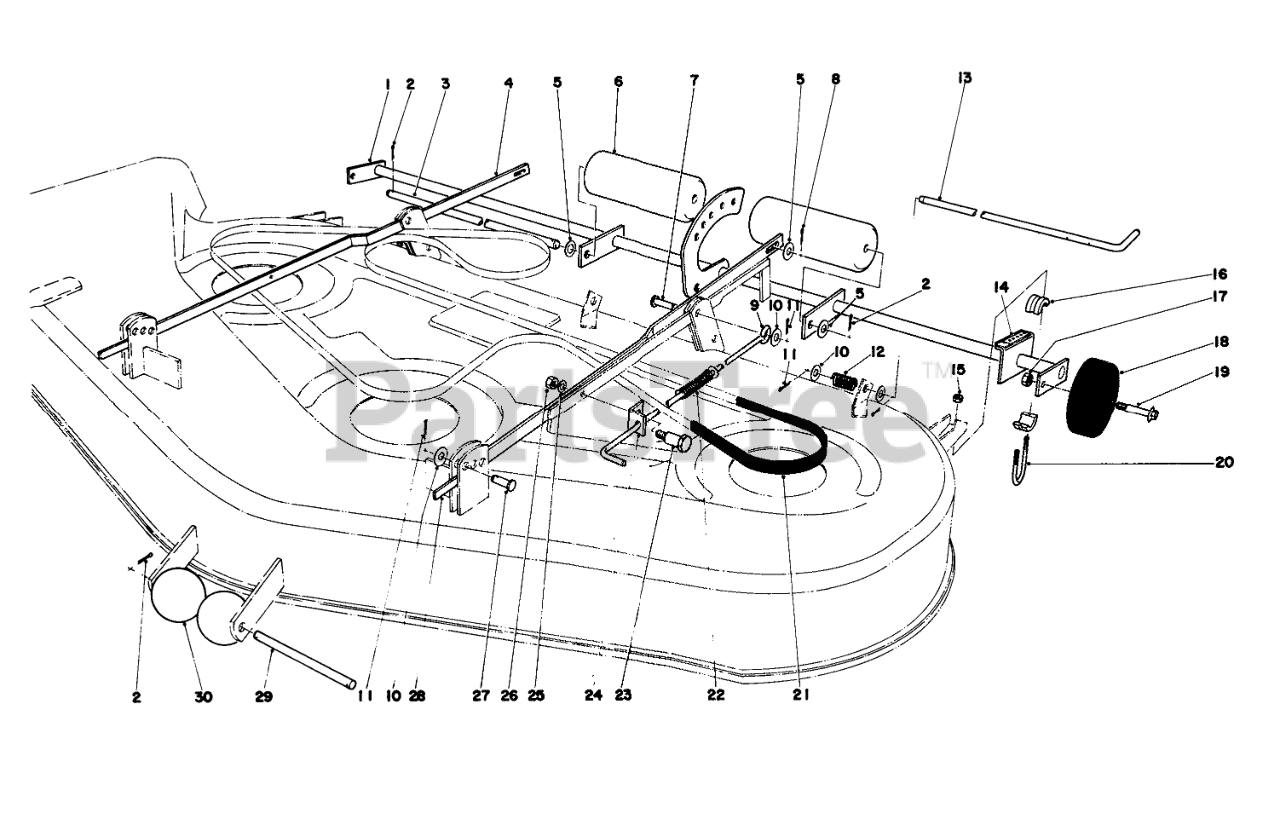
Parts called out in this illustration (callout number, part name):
1	DECK WHL SHAFT WA B
2	PIN-COTTER
3	ROLLER SHAFT B
4	RR SCISSORS LNK B
5	WASHER-FLAT
6	ROLLER-DECK
7	PIN-CLEVIS
8	PIN-COTTER
9	Pin Tension
10	WASHER-FLAT
11	PIN-COTTER
12	Spring
13	WHEEL LATCH ROD B
14	Decal-Height of Cut
15	NUT-LOCK, CONE
16	BEARING DECK SH WHEEL
17	Nut
18	DECK WHEEL
20	U-BOLT
21	V-BELT, DECK
22	COMP SPRING
23	Bolt-Shoulder
24	TENSION BELT BRKT B
25	WASHER-PLAIN
26	NUT-LOCK, CONE
27	PIN-CLEVIS
28	Scissors Link Rear L.H.
29	ROLLER SHAFT
30	Roller
